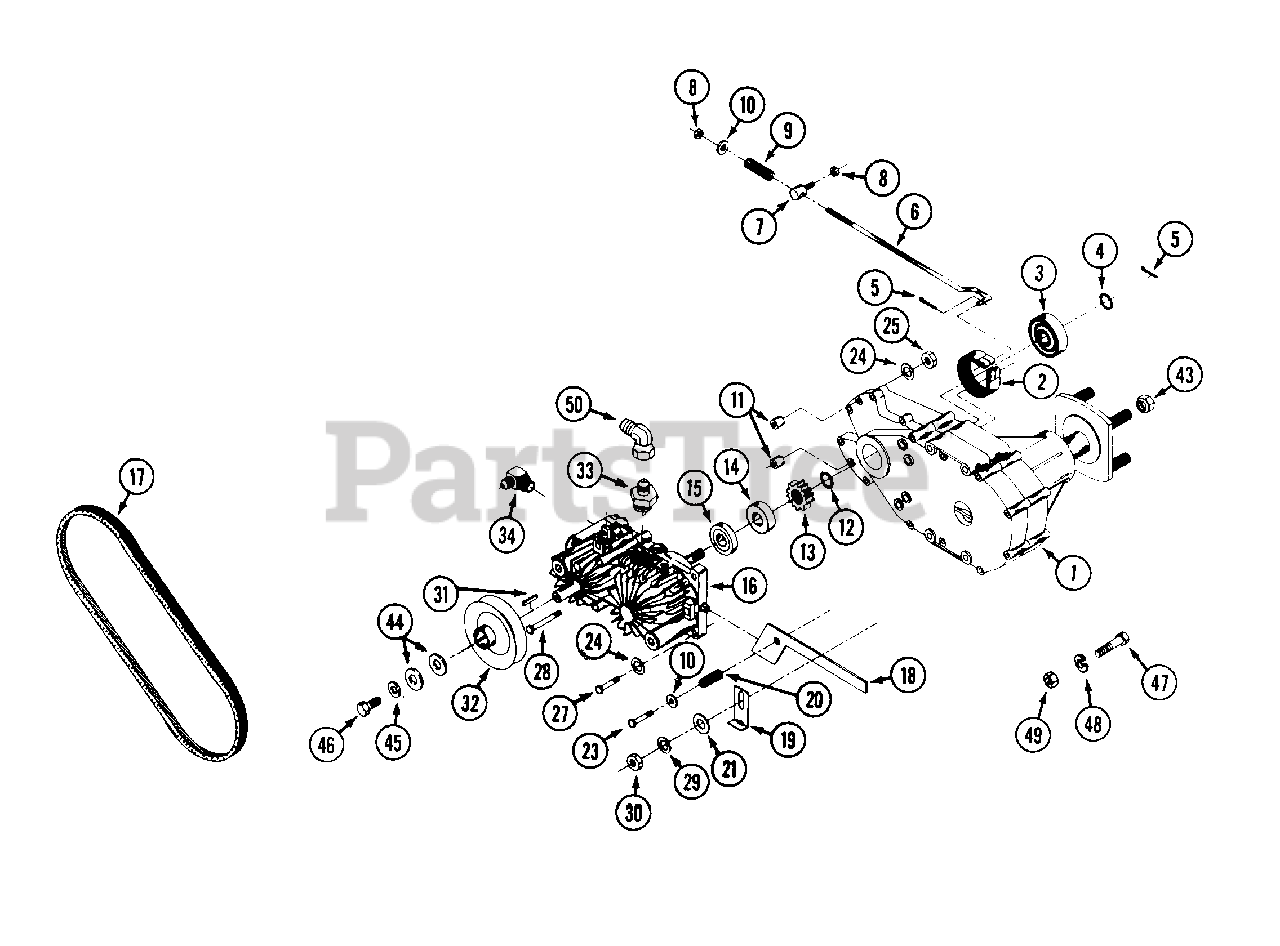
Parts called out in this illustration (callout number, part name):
1	TRANSMISSION - ZT
5	PIN - cotter 1/8" x 1"
8	NUT - lock 1/4" - 20
10	WASHER - 1/4"
12	RING - snap
14	BEARING
16	PUMP - hydro L.H.
17	BELT - pump drive
18	LEVER - transmission dump L.H.
19	BRACKET - dump lever stop
20	SPRING - compression
21	WASHER - 3/8"
23	BOLT - dump lever
24	LOCKWASHER - 5/16"
25	NUT - 5/16" - 18
27	BOLT - 5/16" - 18 x 1-3/4"
28	BOLT - 5/16" - 18 x 7-1/2"
29	LOCKWASHER - 3/8"
30	NUT - 3/8" - 16
31	KEY-5x 5x 25mm
32	PULLEY - 4"
33	FITTING - male adapter
34	FITTING - male adaptor 90°.
43	NUT - lug 1/2" - 20
44	WASHER - .625" x 1"
45	WASHER - .312" x .875"
46	BOLT - M6 - 1.0 x 12 mm flange
47	BOLT - 3/8" - 16 x 3-1/2" mounting
48	LOCKWASHER - 3/8"
49	NUT - 3/8" - 16
50	FITTING - 45° male to female
